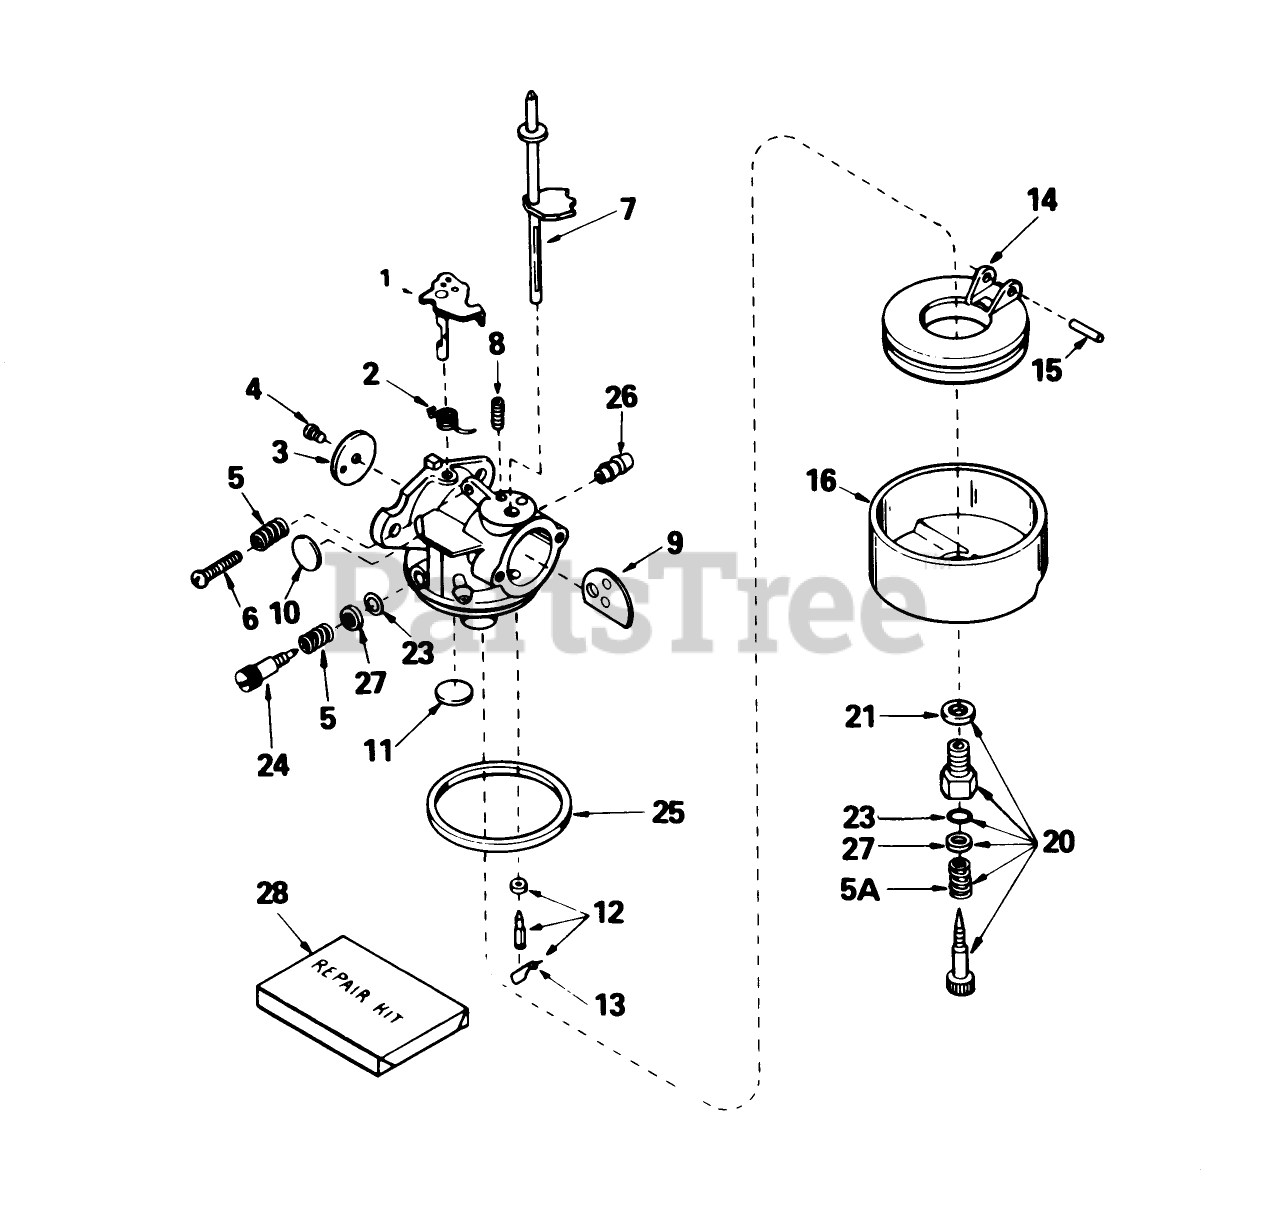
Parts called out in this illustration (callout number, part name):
1	Shaft/Lever-Throttle
2	Spring-Return, Throttle
3	Shutter-Throttle
4	Screw-Shutter
5	Spring-Tension
5A	Spring
6	Screw-Throttle Crack Screw / Idle Speed
7	Shaft-Choke
8	Spring-Positioning, Choke
9	Shutter-Choke
10	Plug-Welch, Idle Mixture Well
11	Plug-Welch, Atmospheric Vent
12	Inlet Needle, Seat Clip Assy. (Incl. No. 13)
13	Clip-Spring
14	Float
15	Shaft-Float
16	Bowl-Float (no drain)
20	Adjustment Screw Assy., Main (Incl. Nos. 5A, 21 23)
21	Washer-Bowl Nut
23	ORing
24	Screw, Idle Adj.
25	O Ring-Bowl, Float
26	Fitting-Fuel
27	Washer
28	Repair Kit (Incl. items marked *)
